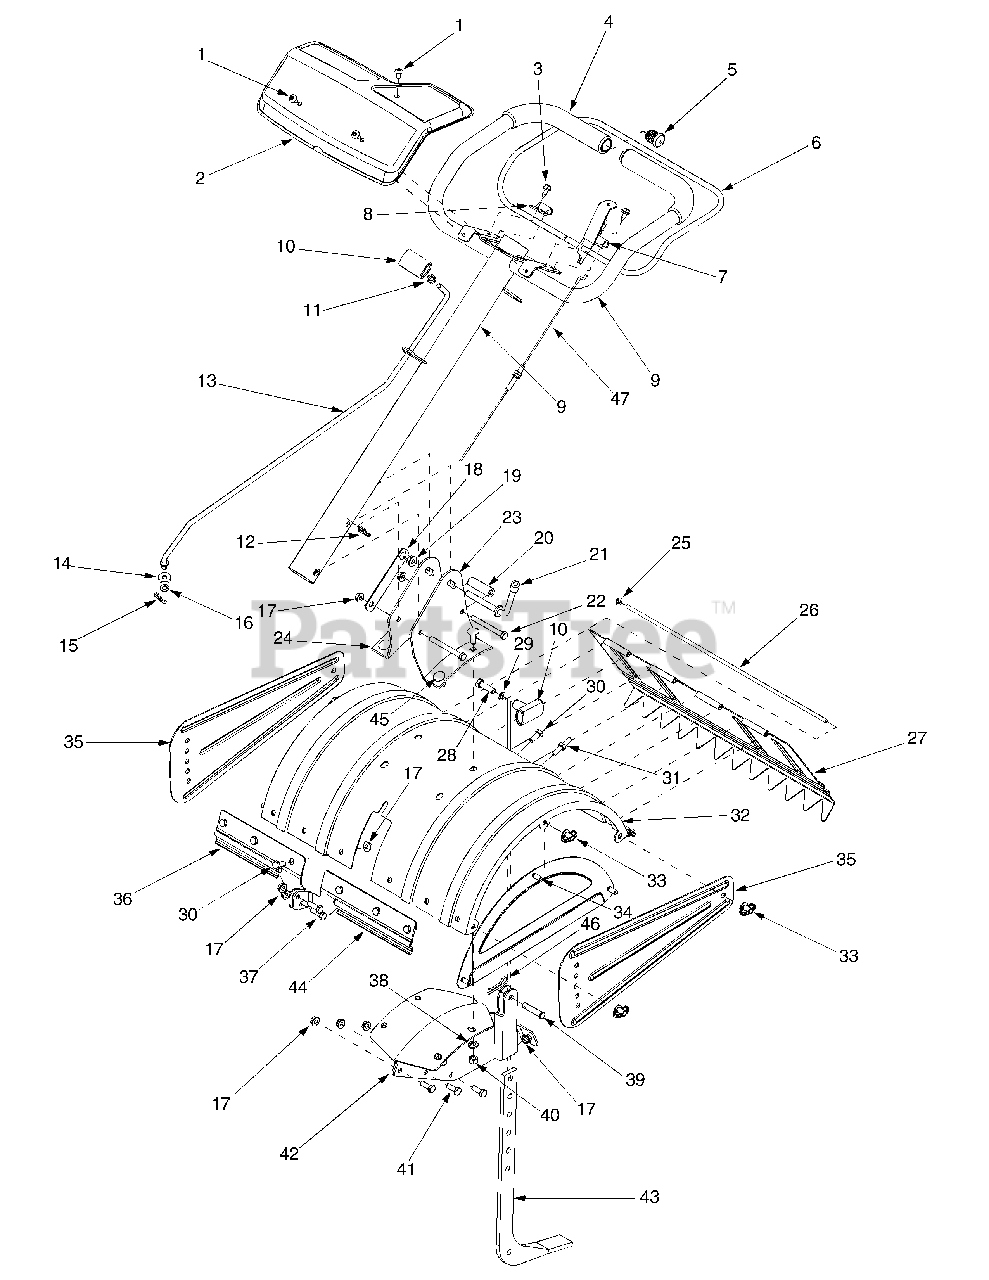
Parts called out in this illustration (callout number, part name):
1	Tap Screw 1/4-14 x.625
4	Foam Grip
5	End Plug
11	Jam Nut 3/8-16
12	Cable Clip
13	Shift Control
14	Rubber Washer.33 ID x.87 OD
15	Cotter Pin
16	Flat Washer.344 ID x.62 OD
17	Hex Flange Lock Nut 5/16-18
18	Retainer Bracket
19	Flange Lock Nut 3/8-24
20	Spacer.322 ID x.625 OD
21	Handle Adjustment Crank
22	Hex Screw 5/16-18 x 3.0
28	Hex Cap Screw 3/8-16 x 1.25
29	Flat Washer.375 ID x.620 OD
30	Hex Cap Screw 5/16-18 x.75
31	Hex Screw 5/16-18 x.75
37	Hex Cap Screw 5/16-18 x 1.0
38	Lock Washer 3/8
39	Clevis Pin
40	Hex Nut 3/8-16
41	Hex Cap Screw 5/16-18 x.875
45	Carriage Bolt 3/8-16 x 1.0
46	Cotter Pin
47	Clutch Cable
